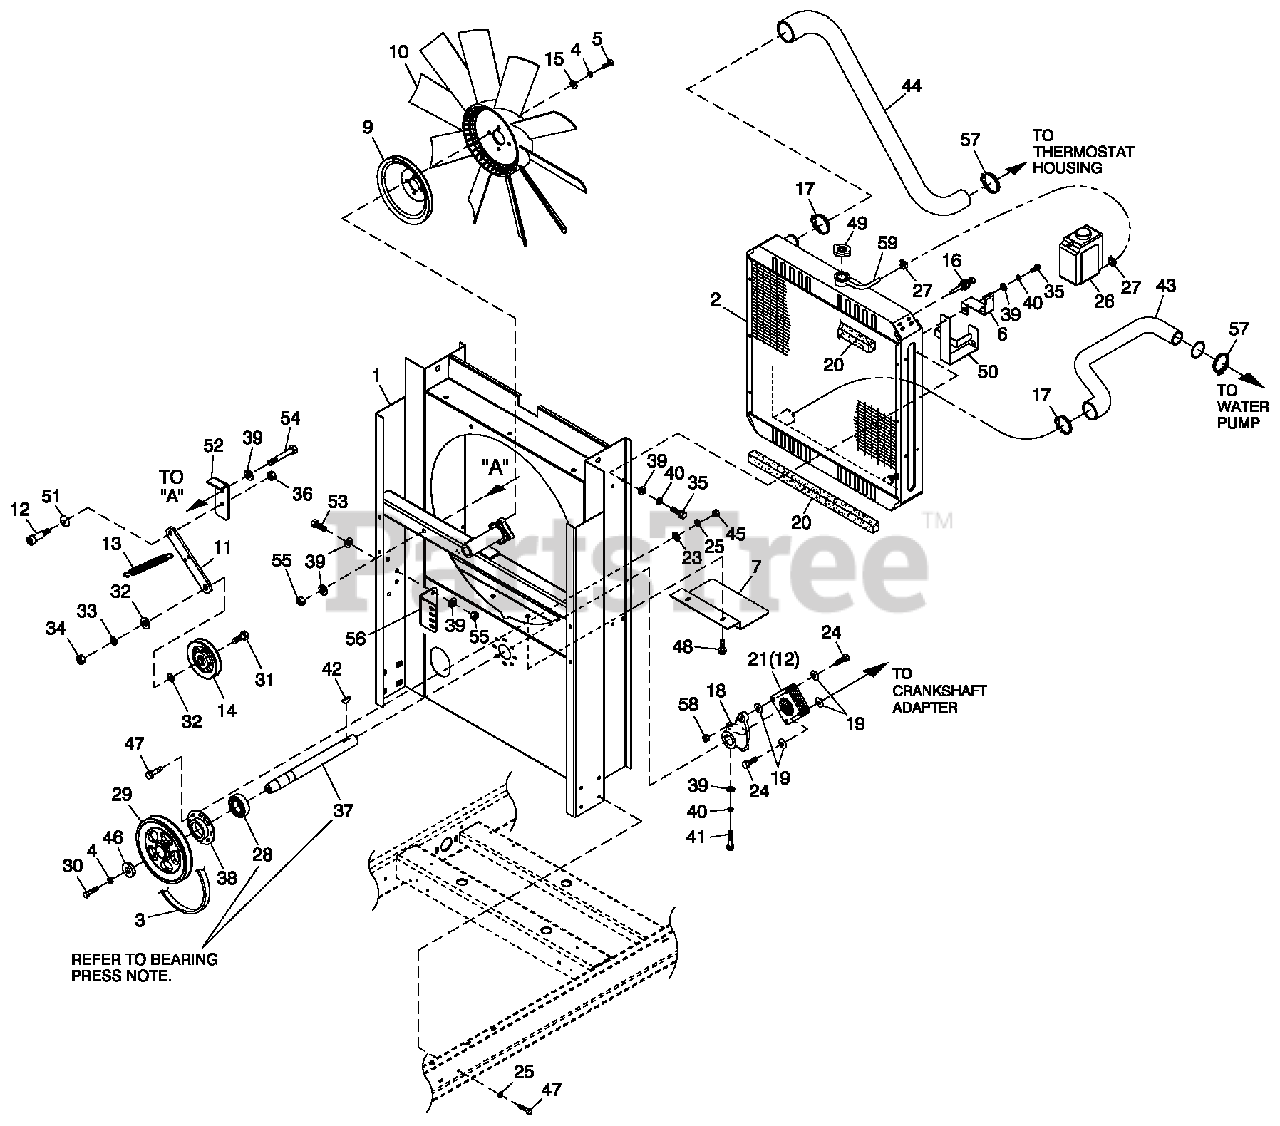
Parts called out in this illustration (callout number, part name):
1	WELDMENT RADIATOR SUPPORT C2
2	RADIATOR 598 X 568 X 49 CPL RH
3	V- BELT 31/64" X 57-3/8"
4	WASHER LOCK M10
5	SCREW HHC M10-1.5X30G10.9
6	BRACKET, SIGNAL CONDITIONER (USED ONLY WITH QTA PRODUCT)
7	SHIELD RADIATOR C4
9	PULLEY FAN V-GROOVE 9"
10	FAN COOL 22" DIA 10 BLADE LH
11	FLATTENSIONERARM
12	SHOULDER BOLT 3/8 X 1/2"
13	SPRING TENSION CPL
14	PULLEY V- BELT 4" FLANGED
15	WASHER FLAT 3/8-M10 ZINC
16	PRO BE COOLANT LEVEL 3/8 NPTF
17	CLAMP HOSE #28 1.32-2.25
18	HU B FLEX PLATE
19	WASHER FLEX (THIN)
20	TAPE FOAM 1 X 1 (26.75" LG)
21	DISK FLEX
23	WASHER FLAT 1/4-M6 ZINC
24	SCREW HHC 5/16-24X1.124
25	WASHER LOCK M6-1/4
26	TANK COOLANT RECOVERY
27	CLAMP HOSE BAND 1/4
28	BEARING #6205 2NSE C3 E SRI2 S
29	PULLEY 4.5" DIA MACHINED
30	SCREW HHCM10-1.5X30 G8.8
31	SCREW HHC 1/2-13 X 2" G8
32	WASHER FLAT 1/2 ZINC
33	WASHER LOCK 1/2
34	NUT HEX 1/2-13 STEEL
35	SCREW HHFC M8-1.25 X 20 W/M6
36	NUT HEX LOCK 5/16-18 NY INS SS
37	SHAFT FAN DRIVE
38	RETAINER BEARING
39	WASHER FLAT 5/16-M8 ZINC
40	WASHER LOCK M8-5/16
41	SCREW HHC M8-1.25X35 G8.8
42	KEY WOODRUFF 4X19D
43	HOSE LOWER RADIATOR G2
44	HOSE UPPER RADIATOR G2
45	NUT HEX M6X 1.0 G8YEL CHR
46	SPACER .5 X 1.5 X .25 STL/ZINC
47	SCREW HHFC M6-1.0X 20 G8.8
48	SCREW THF M6-1 X 16 N WA Z/JS
49	CAP RADIATOR 13 PSI
50	BRACKET COOLANT TANK
51	WASHER BELLEVILLE .75X.38X.028
52	TENSIONERARM SUPPORT BENT 90
53	SCREW HHC M8-1.25X20 C8.8
54	SCREW HHC M8-1.25X75 C8.8
55	NUT HEX LOCK M8-1.25 NY INS
56	BRACKET TENSIONER SPRING
57	CLAMP HOSE #24 B1.06-2.00
58	NUT HEX LOCK 5/16-24 NY INS
59	HOSE 9/32 ID (27" LG)
